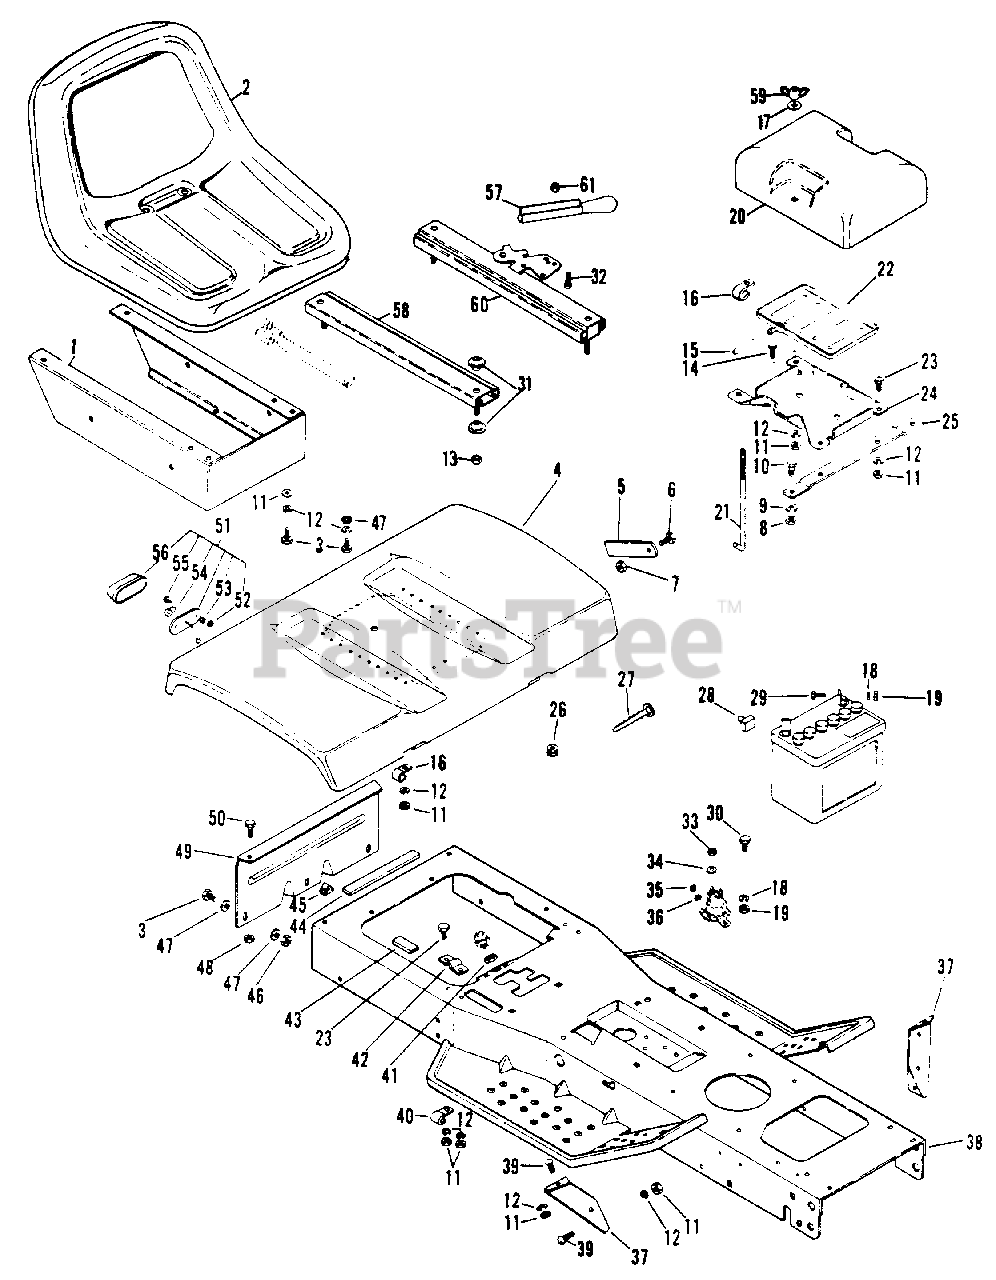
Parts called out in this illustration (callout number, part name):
1	FRAME, SEAT
2	SEAT, HIGH BACK
3	BOLT, HEX 5/16-18X.75
4	DECK, REAR
5	CATCH, DECK
6	BOLT, HEX 3/8-16X.625
7	NUT, LOCK 3/8-16
8	NUT, HEX 3/8-16
9	WASHER, LOCK 3/8 REG.
10	BOLT, HEX 3/8-16X.75
11	NUT, HEX 5/16-18
12	WASHER, LOCK 5/16 SP
13	NUT, LOCK 5/16-18
14	BOLT, HEX 5/16-18X1.00
15	HOSE, DRAIN
16	J-CLAMP
17	WASHER, FLAT .281X.625X.065
18	WASHER, LOCK 1/4 REG.
19	NUT, HEX 1/4-20
20	COVER, BATTERY
21	BOLT, HOLD DOWN
22	TRAY, PLASTIC BATTERY
23	BOLT, HEX 5/16-18X.75
24	TRAY, BATTERY
25	STRAP
26	GROMMET
27	TIE DOWN
28	INSULATOR
29	BOLT, HEX 1/4-20X.875
30	BOLT, HEX 1/4-20X.875
31	SPACER
32	SCREW, MACHINE 10-24 X.625 P/HD
33	NUT, JAM 5/16
34	WASHER, LOCK 5/16 INT. TOOTH
35	NUT, HEX 10-32
36	WASHER, LOCK #10 EXT.
37	STRUT, L.H. FOOTBOARD
37	STRUT, R.H. FOOTBOARD
38	FRAME, MAIN
39	BOLT, CARRIAGE 5/16-18X.75
40	J-CLAMP
41	NUT
42	BRACE
43	TAPE, FOAM
44	TAPE, FOAM
45	BUMPER
46	NUT, LOCK 5/16-18
47	WASHER, FLAT .406X.812X.065
48	NUT, LOCK 3/8-16
49	DRAWBAR
50	BOLT, HEX 3/8-16X1.25
51	ASSEMBLY, TAILLIGHT
52	NUT, 10-24 HEX
53	WASHER, LOCK NO. 10 SP
55	SCREW, MACHINE 10-24X.50 PHD
56	LENS
57	HANDLE, SEAT ADJUSTER
58	ADJUSTER, SEAT
59	NUT, WING 1/4-20
60	ADJUSTER, SEAT W/LATCH
61	NUT, LOCK 10-24
NS	DECAL, TRACTOR(SAFETY/CONTROLS)
NS	DECAL, AMERICA
NS	DECAL, GRAVELY LOGO
